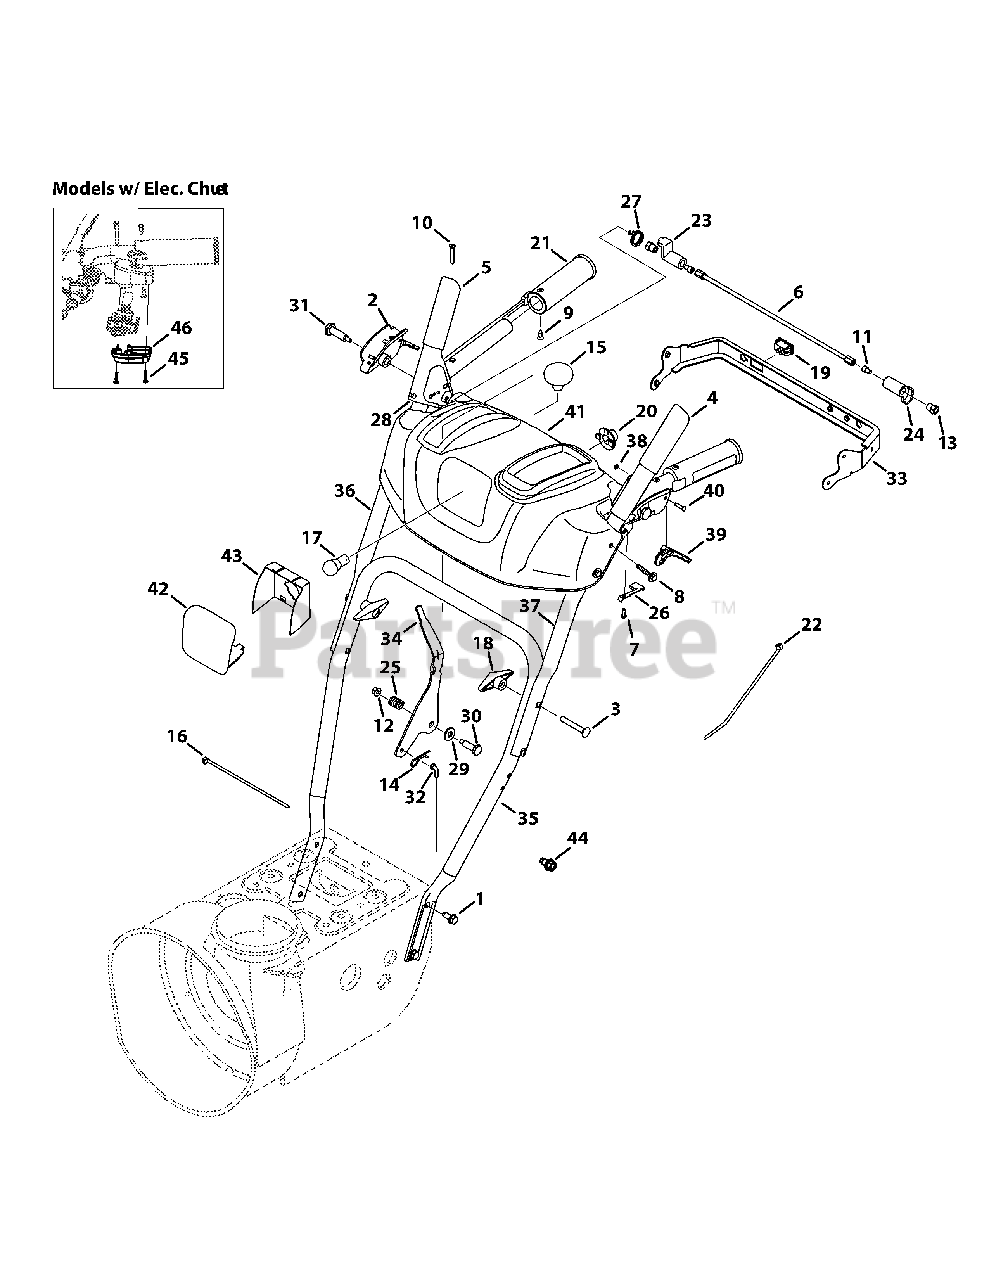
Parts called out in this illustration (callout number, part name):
1	Screw, Taptite, 5/16-18 x .750
2	Clutch Lock, RH
2	Clutch Lock, RH (Elec. Chute)
2	Clutch Lock, LH
3	Screw, Carriage, 5/16-18 x 2.50
4	Auger Engage, Black, LH
5	Drive Engage, Black, RH
6	Pivot Rod
7	Screw, Plastite, 8-16 x .50
8	Screw, Taptite, 1/4-20 x 1.625
9	Screw, 10-16 x 0.625
10	Screw, 10-24 x 1.375
11	Screw, 1/4-20 x .50
12	Nut, Flangelock, 1/4-20
13	Nut, Hex, 1/4-20
14	Click Pin, .092 x 1.64
15	Shift Knob
16	Cable Tie, 7"
18	Wing Knob, 5/16-18
19	Heated Grip Switch
20	Lamp Socket
21	Heated Grip
21	Grip, 1.0 ID x 5.0 LG
22	Cable Tie, Push Mount
23	Plate, Lock
24	Cam, Clutch Lock
25	Compression Spring, .39 x .60 x .88
26	Clutch Lock Spring
27	Torsion Spring, 0.8156 x .3038
28	Rubber Bumper
29	Washer, Flat, .385 x .87
30	Screw, Shield, .374 x 1.05
31	Screw, Shoulder, .437 x 1.345 x 1/4-20
32	Speed Selector Cable
33	Panel Bracket
34	Shift Lever
35	Lower Handle
36	Upper RH Handle
37	Upper LH Handle
38	E-Ring
39	Steering Trigger Control
40	Steering Trigger Pin, 3/16
41	Handle Panel, Gray
41	Handle Panel, Black
42	Lens Panel
43	Lens Label
44	Screw, TT, 1/4-20 x .500 (For ground wire)
45	Screw, .159 OD x .610
46	Housing Cover (Elec Chute)
